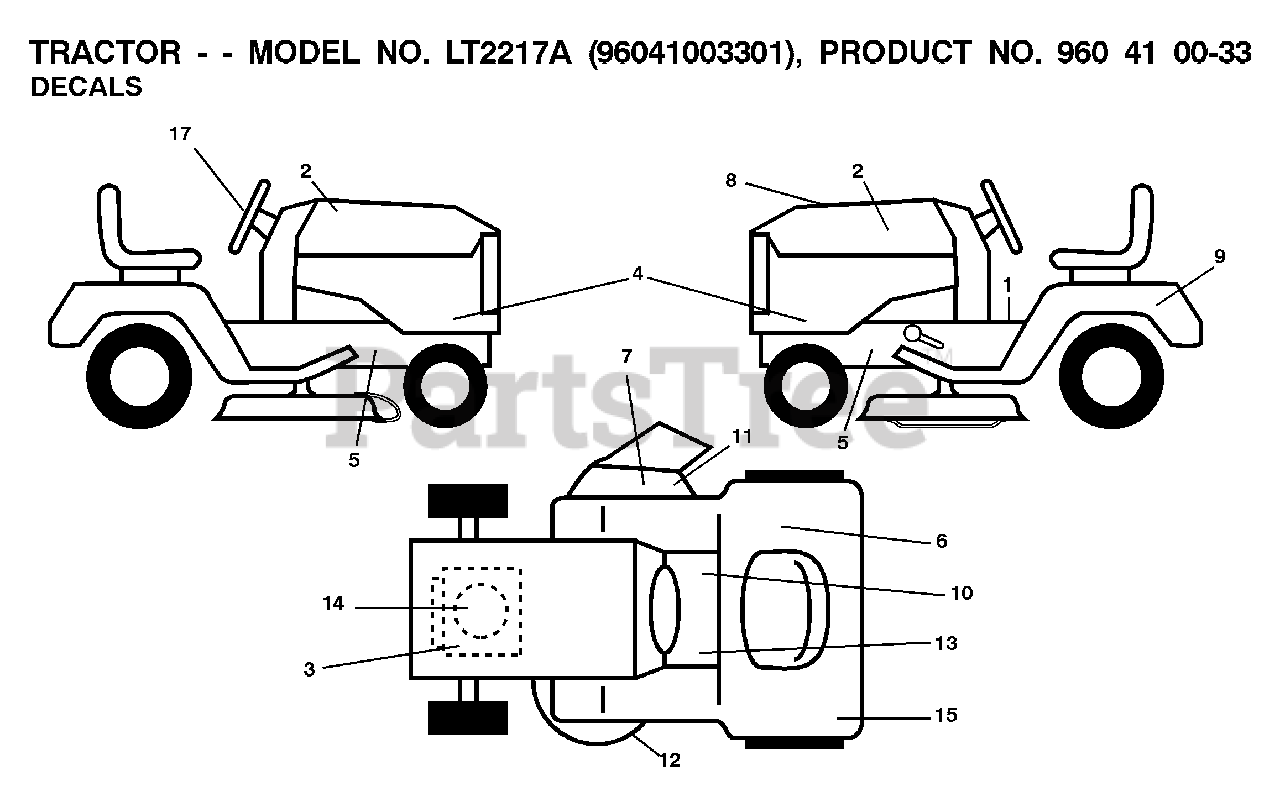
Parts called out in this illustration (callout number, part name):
7	DECAL.INTERNATIONL.CUTFINGER
9	DECAL BTRY SYMBOLS
10	DECAL PARK BRAKE
11	DECAL, DEFLECT WARNING
12	DECAL.V-BELT.SCHEMATIC.36/38/9
